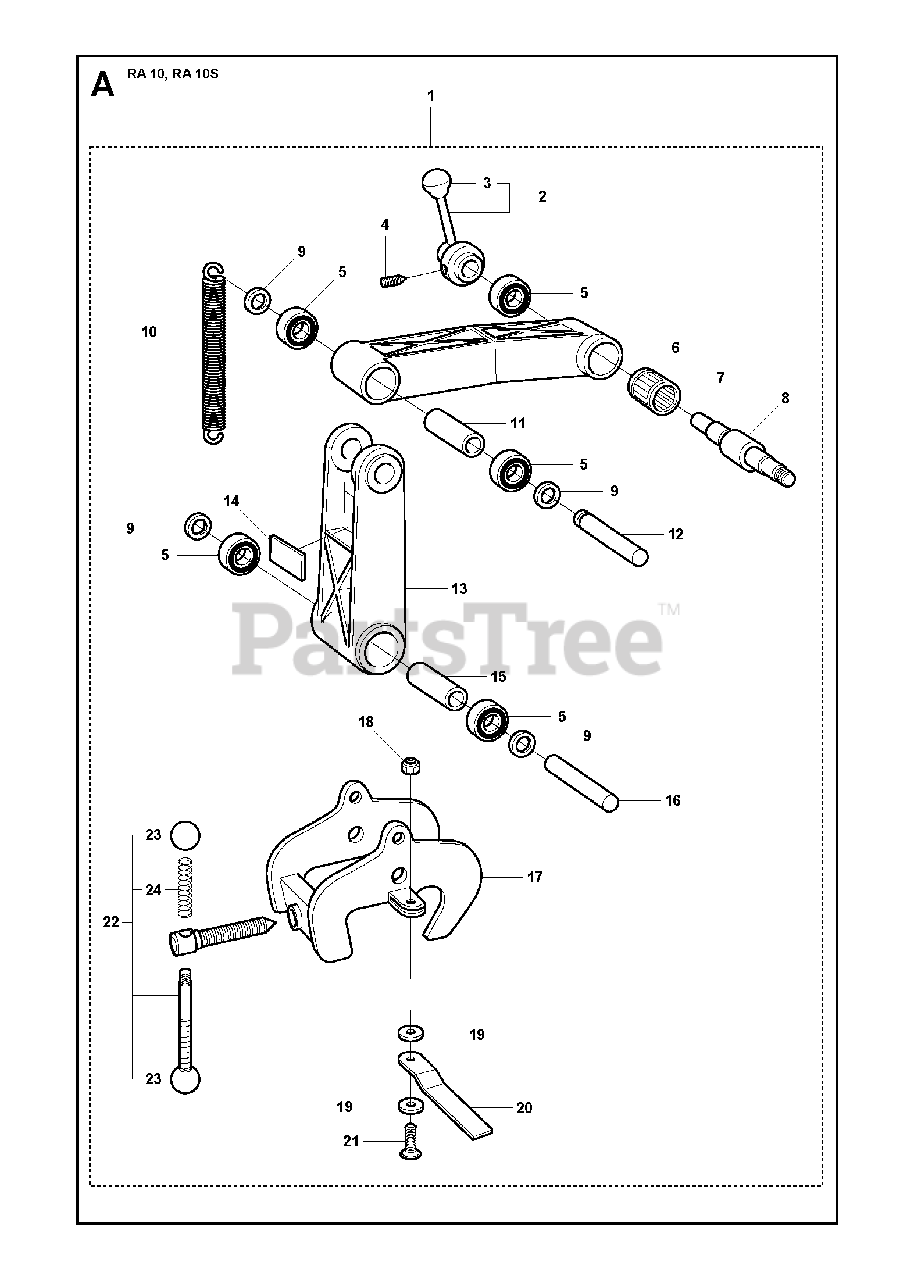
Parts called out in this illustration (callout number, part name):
1	RAIL FIXTURERA10. Incl. 2, 4 - 22
1	RAIL FIXTURERA10 S. Incl. 2, 4 - 22
2	LOCKING HANDLEIncl. 3
5	BALL BEARING
17	RAIL ATTACHMENTRA10 S
18	NUT
21	SCREW SLCSFM
22	LOCKING HANDLERA10. Incl. 23, 24
22	LOCKING HANDLERA10 S. Incl. 23, 24
